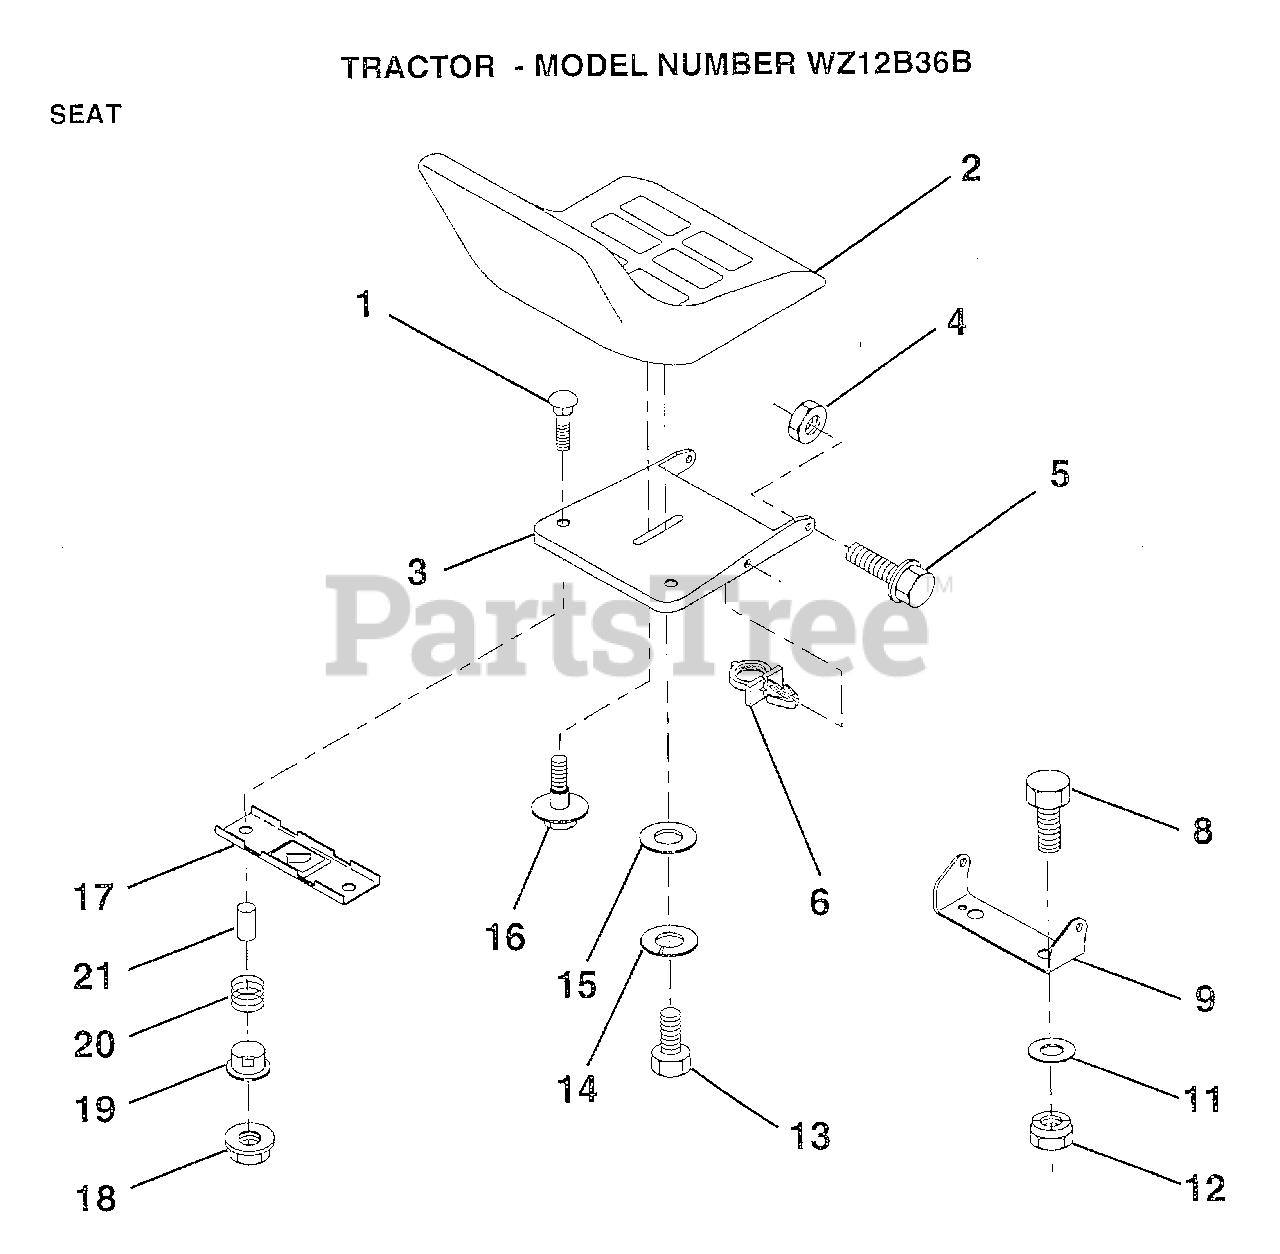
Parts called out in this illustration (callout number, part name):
1	BOLT-RD HD SQ NK
3	PAN-SEAT
4	NUT
5	"BOLT,SHOULDER"
6	CLIP.PUSH-IN.HING
8	BOLT
9	BRACKET PVT SEAT
11	WASHER
12	NUT
13	BOLT
14	LOCKWASHER
15	WASHER
16	"BOLT,SHOULDER"
17	BRKT SWITCH
19	BUSHING
20	SPRING
21	SPLIT SPACER
